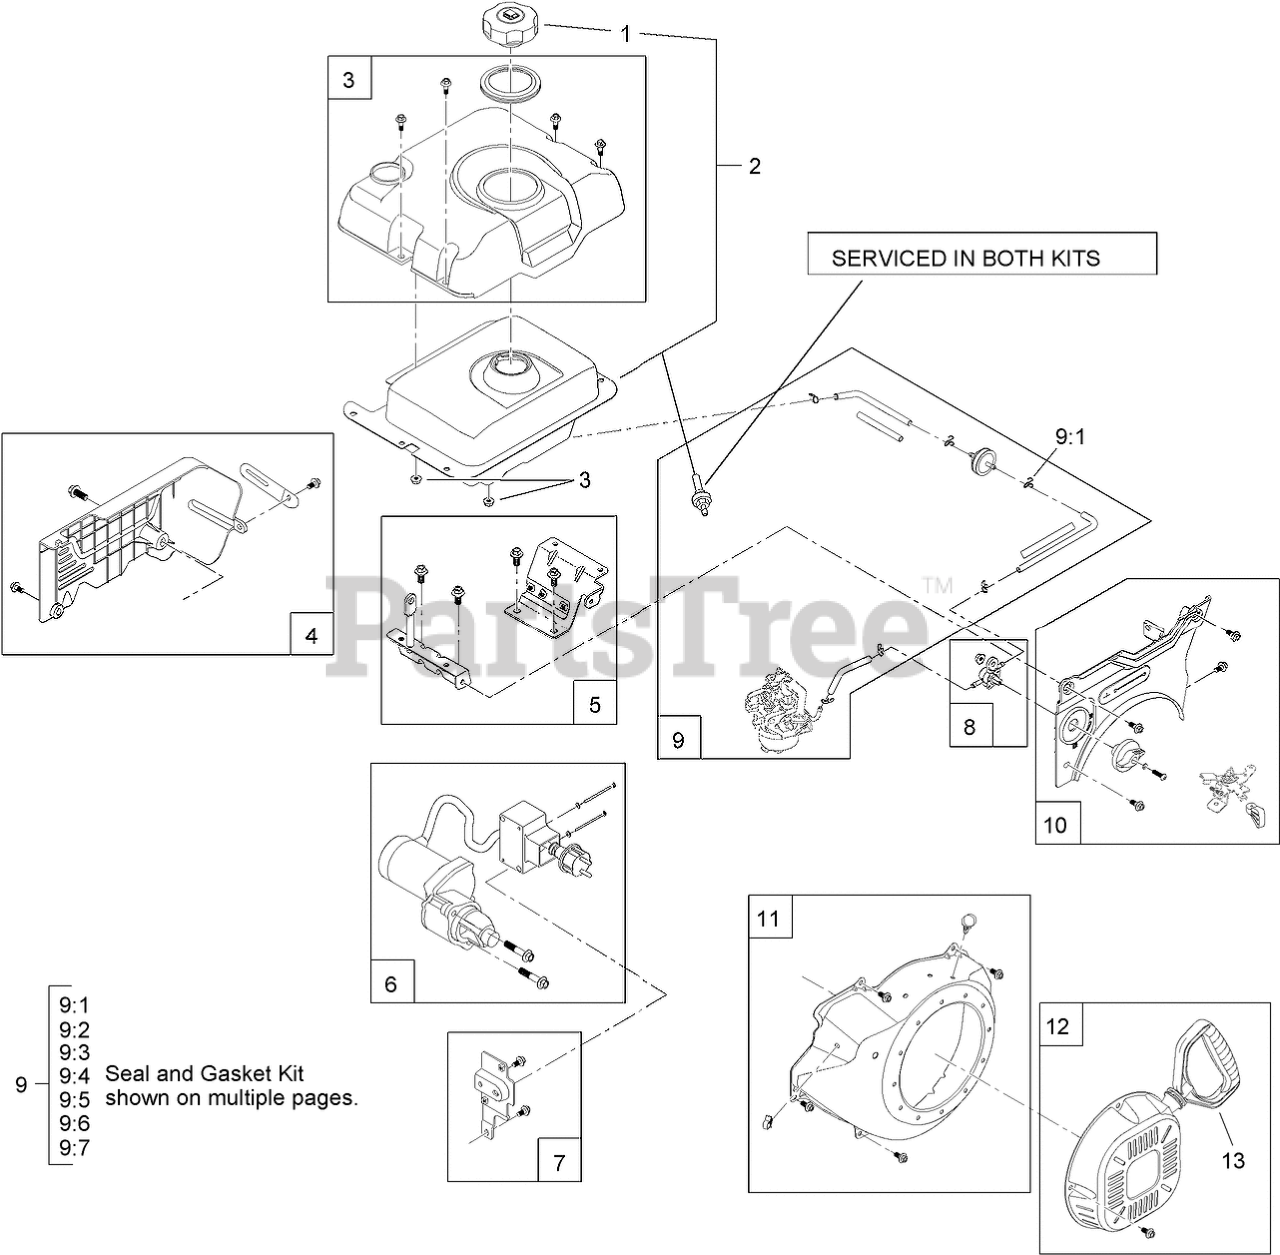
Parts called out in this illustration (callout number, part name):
1	CAP-FUEL (PHASE 3)
2	FUEL TANK AND CAP KIT
3	FUEL TANK COVER KIT
4	REAR PANEL AND HARDWARE KIT
5	TANK MOUNT BRACKET KIT
6	STARTER KIT
7	SWITCH BOX BRACKET KIT
8	FUEL SHUT-OFF VALVE KIT
9	COMPLETE FUEL LINE KIT
9:1	Clamp-Hose
9:2	Hose-Fuel
9:3	Hose-Fuel
9:4	SLEEVE-ABRASION
9:5	Filter-Fuel
9:6	Hose-Fuel
9:7	SLEEVE-ABRASION
10	FRONT PANEL KIT
11	RECOIL SHROUD KIT
12	RECOIL KIT
13	HANDLE-RECOIL
